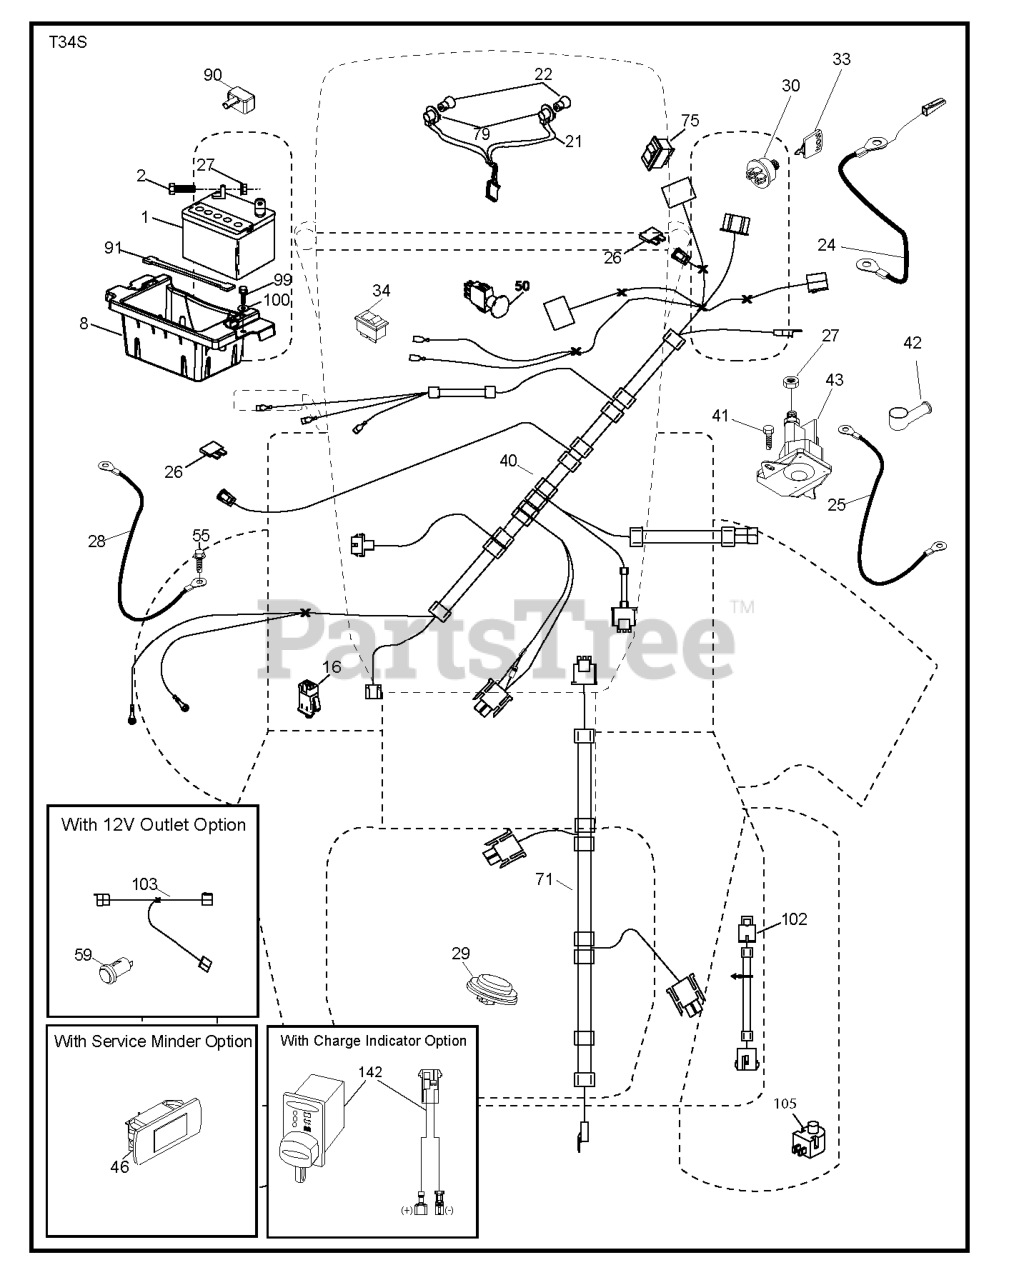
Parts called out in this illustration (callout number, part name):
1	Battery, Dry 30 Amp
2	BOLT.HEX.1/4.X.3/4.DICHROMATE
8	BOX.BATTERY.MOUNT.FRONT.LT
16	SWITCH INTERLOOK PUSH-IN
21	HARNESS.LIGHT W/4152J BULBS
24	CABLE.BATT.POS.WIRE.TG.DA SOL
25	CABLE.STARTER.6G.BL/RED.17.5
26	FUSE 20AMP
27	NUT
28	CABLE GROUND 6 GA 21" 90T BLK
29	SWITCH.SEAT.DELTA.OPC.
30	SWITCH.IGN.DELTA.W.LGH.ROS
33	KEY.CHAIN.BLISTER.PACK.GEN.USA
40	HARNESS.IGN.DASH.HUSQ/PRED.
41	SCREW
42	TERMINAL COVER
43	SOLENOID.W/BRASS.PLUNGER
46	RP.GUAGE.SRVCMNDR.HRMTR.
50	RP.PTO.SWITCH.8 TERMINAL.BLACK
55	SCREW 5/16"
71	HARNESS.IGN.CHASSIS.TEX.DCKLOC
75	SWITCH.ON/OFF.(DIFF.LOCK)
79	BULB HOLDER ASM.
90	COVER.TERMINAL.BATTERY
91	STRAP.BATTERY.MOUNT.FRONT(2 2)
99	SCREW HEXWSHR 1/4-20X3/4
100	WASHER
102	HARNESS PIGTAIL PCH TEX ROS
105	REVERSE SWITCH
142	RP HARNESS.JUMPER.CTEK
